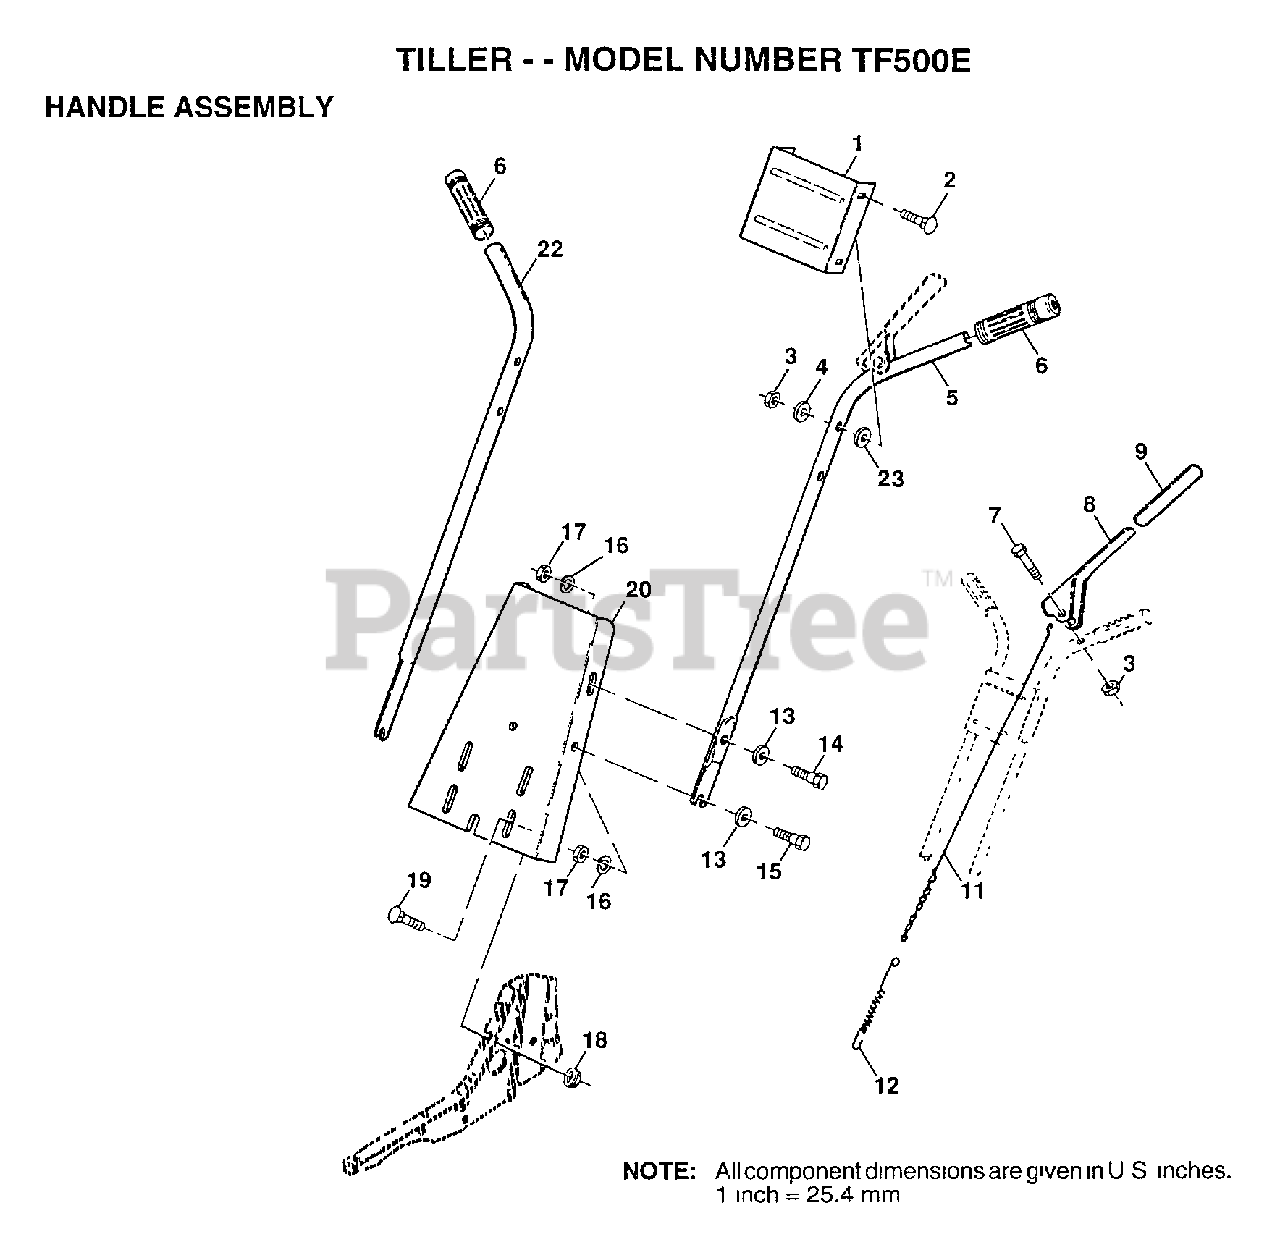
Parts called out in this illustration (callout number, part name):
1	PANEL.CNTRL.HDLE.
2	BOLT
4	WASHER
5	HANDLE LH
7	BOLT.HEX.5/16-1.5
9	GRIP T
12	SPRING EXT TI
13	WASHER
15	BOLT
16	LOCKWASHER
17	NUT.HEX.5/16-18
18	NUT
19	BOLT
20	PANEL.HANDLE.TILL
22	HANDLE RH
23	WASHER
